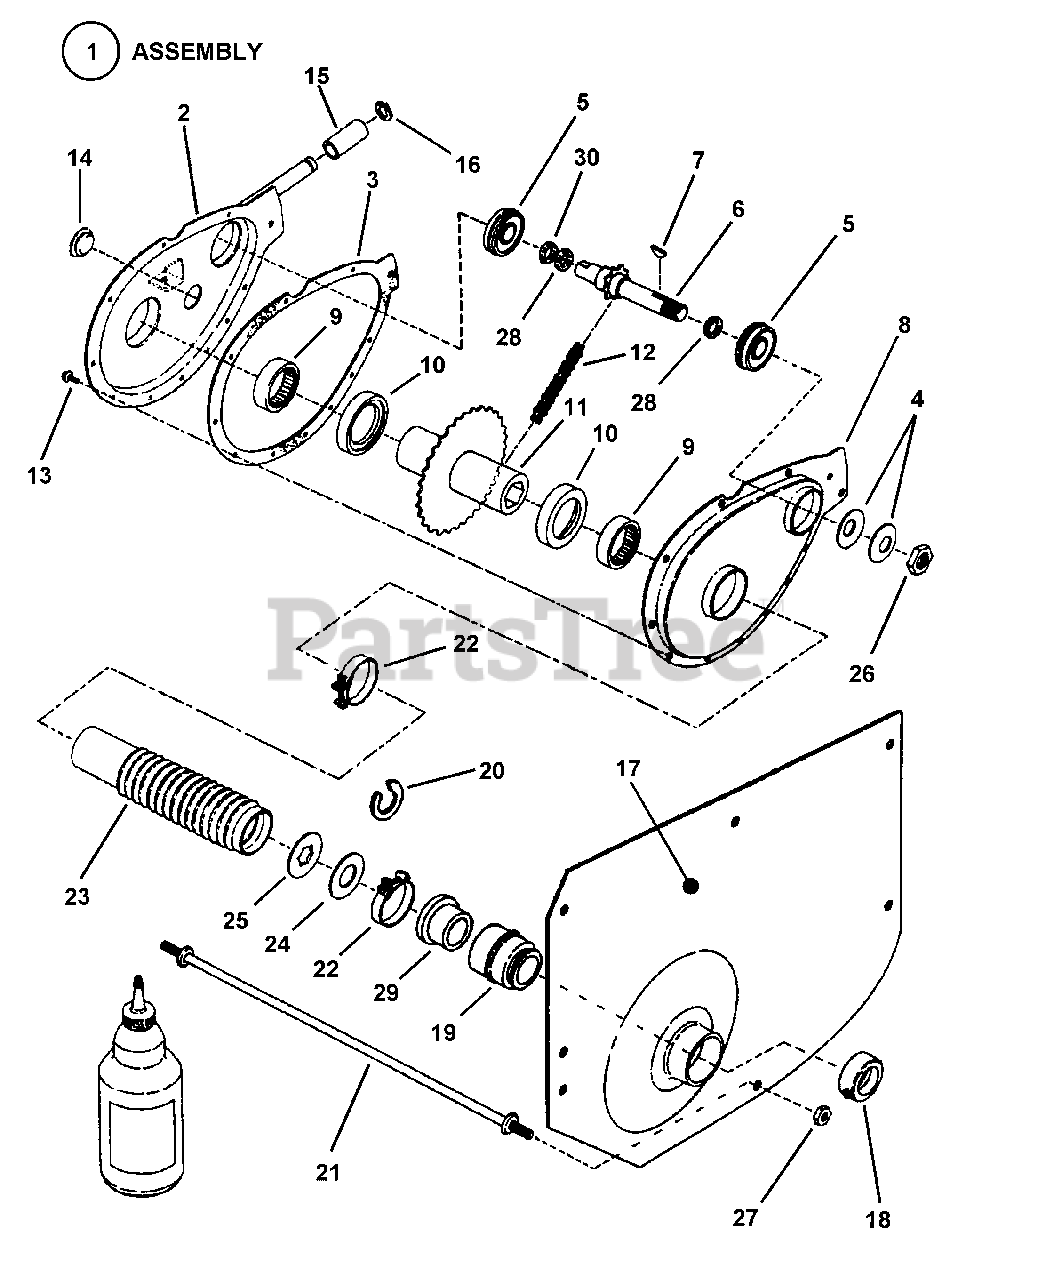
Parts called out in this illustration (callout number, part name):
1	ASSEMBLY, Chain Case
2	CASE, Sprocket (Weldment)
3	GASKET, Case Cover
4	WASHER, Belleville
5	BEARING, Ball
6	SPROCKET & SHAFT
7	KEY, 1/8 x 5/8" Woodruff
8	COVER, Chain Case
9	BEARING, Needle
10	WASHER, Nylon Thrust
11	HUB & SPROCKET (Weldment)
12	CHAIN, 46 Pitch (#35)
13	SCREW, #10-24 x 1/2" Hex Washer Self-Tap (Torx)
14	PLUG, Oil Fill & Check
15	ROLLER
16	RING, 1/2" External Retaining
17	FENDER, Left Hand (1.744" I.D. Hole)
17	FENDER & BEARING ASSY, LH (Ball Bearing)
18	COLLAR, Lock
19	BEARING, Left Hand Fender
20	WASHER, Shim
21	ROD, Cross-Tie
22	CLAMP, Boot, 2"
23	BOOT, Oil Seal
24	WASHER, Thrust Nylon
25	WASHER, Thrust
26	NUT, 5/8-18 Hex Nyloc
27	NUT, 5/16-24 Hex Flange Lock
28	O-RING
29	SPACER
30	WASHER, Wave
